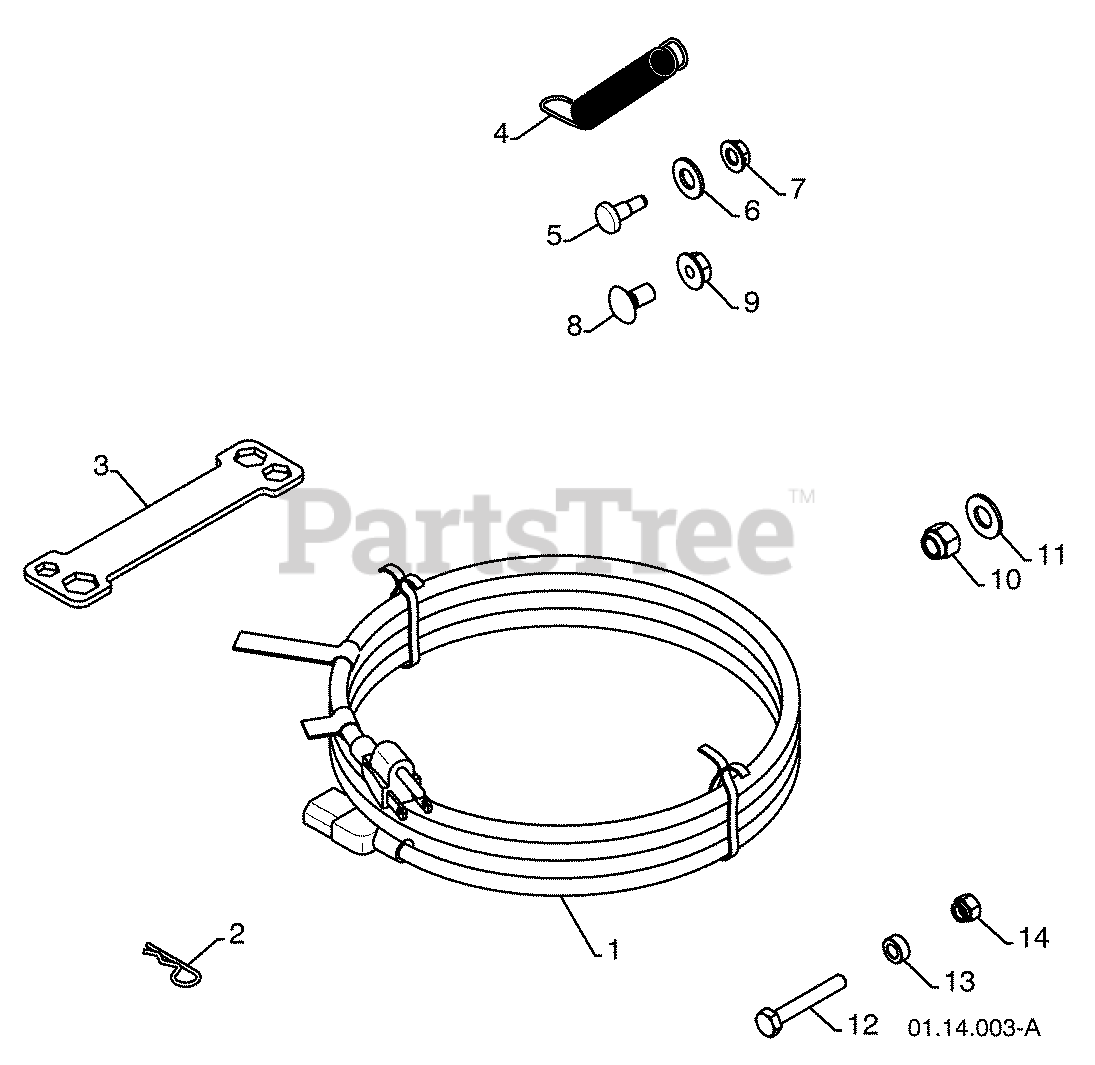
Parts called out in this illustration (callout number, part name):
1	POWER CORD
2	RETAINER PIN
3	WRENCH
4	REMOTE SPRING
5	SHOULDER BOLT 1/4-20
6	NYLON WASHER 1/4-20
7	LOCKNUT 1/4-20
8	CARRIAGE BOLT 5/16-18 X 5/8
9	LOCKNUT 5/16-18
10	LOCKNUT 3/8-16
11	WASHER 3/8
12	SHEAR BOLT 1/4-20 X 1-3/4
14	LOCKNUT 1/4-20
